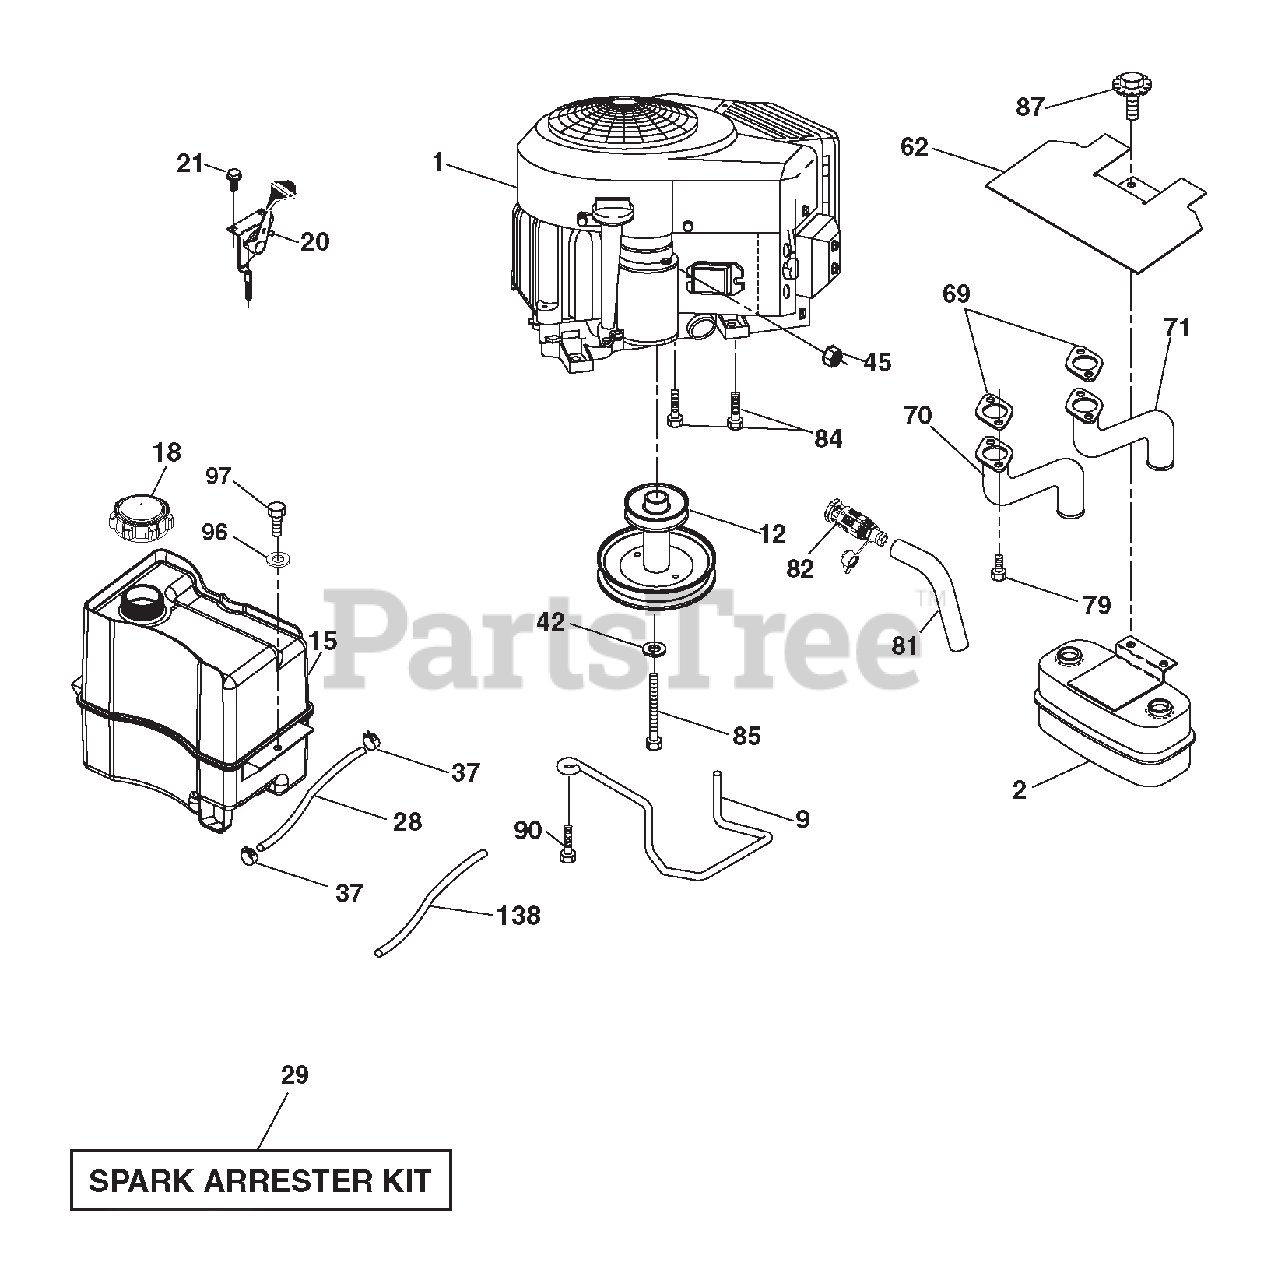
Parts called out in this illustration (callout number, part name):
1	ENGINE BRIGGS MODEL NO. 407777-3195-G5 (581081901)(ORDER PARTS FROM ENGINE MANUFACTURER.)
2	MUFFLER ASM.TWIN.LO-TONE
9	KEEPER BELT ENGINE
12	PULLEY.ENGINE.5.0.P.D.
15	TANK.FUEL.2.5.GAL.
18	CAP FUEL
20	CONTROL THROTTLE/CHOKE
28	LINE.FUEL.20"
29	KIT.SPARK ARRESTOR(392390 B&S)
37	CLAMP.HOSE.BLK.
42	WASHER.LOCK.HVY HLCL.SPR.7/16
45	Nut, Keps Hex 1/4-20 unc
62	SHIELD.HEAT.MUFFLER.
69	GASKET MUFFLER
70	EXHAUST TUBE LH
71	EXHAUST TUBE RH
79	SCREW SOCKET HEAD 5/16-18 X 1
81	TUBE.DRAIN.OIL.EASY
82	VALVE OIL DRAIN
84	Screw 3/8-16 x <
85	BOLT.HEX.7/16-20X4XGR5-1.5THR.
87	BOLT.5/16-18UNCX3/4 W/SEMS.BLK
90	SCREW.3/8-16X1.SMGML.TAP/R.BLK
96	WASHER.9/32 X 7/8 X 16GA.
97	SCREW.HEXWSH.THDROL.1/4-20X3/4
138	PURGE.LINE.CARB
